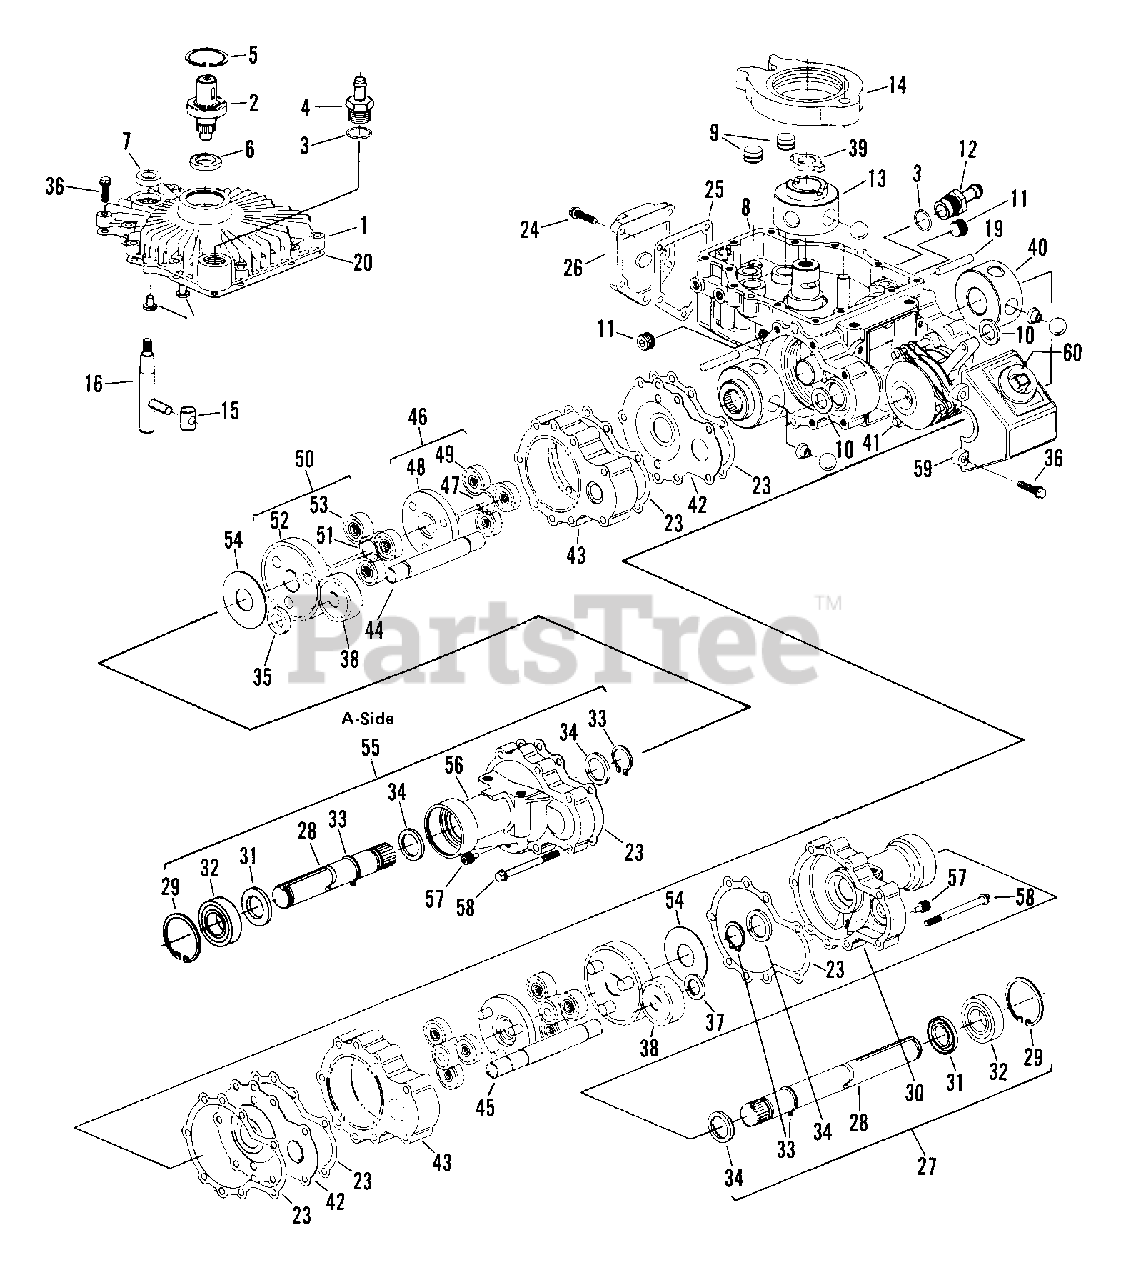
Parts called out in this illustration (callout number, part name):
1	COVER, SUBASSEMBLY
2	INPUT SHAFT SUBASSEMBLY
4	ADAPTER, RESERVOIR, 90 DEGREE
5	RING RETAINING, INT
6	SEAL, INPUT SHAFT
7	SEAL, CONTROL SHAFT
8	HOUSING SUBASSEMBLY
9	PISTON, DAMPENING SUBASSEMBLY
10	SEAL, BRAKE SHAFT
11	PLUG, SOCKET PIPE
12	ADAPTER, RESERVOIR, 3/8 ID
13	PUMP, ROTOR BALL SUBASSEMBLY
14	CAM RING SUBASSEMBLY
16	CONTROL SHAFT SUBASSEMBLY
17	O-RING PLUG SUBASSEMBLY
20	GASKET, COVER
23	GASKET, AXLE HOUSING
24	SCREW, 1/4 -20 HEX FLANGE
25	GASKET, VALVE COVER
26	VALVE COVER
27	AXLE HOUSING SUBASSEMBLY - B
28	SHAFT, AXLE - B
28	SHAFT, AXLE - A
29	RETAINING RING, INT.
30	HOUSING, AXLE - B
31	SEAL, AXLE SHAFT
32	BEARING, AXLE SHAFT
33	RETAINING RING, EXT. - B
34	WASHER, THRUST
35	AXLE HOUSING SUBASSEMBLY - A
36	SCREW, 1/4-20 SELF TAP
37	AXLE HOUSING SUBASSEMBLY - B
38	BRAKE GEAR
40	MOTOR ROTOR-BALL SUBASSEMBLY
41	BRAKE ASSEMBLY - 50 DEGREE
42	PLATE, WEAR
43	RING GEAR SUBASSEMLBY
44	BRAKE SHAFT - A
45	BRAKE SHAFT - B
46	PLANETARY GEAR, FIRST S/A
47	SUN GEAR, FIRST, 18T
48	PRIMARY CARRIER, S/A 18T
49	PLANET GEAR, FIRST, 18T, S/A
50	PLANETARY GEAR, SECOND S/A
51	SUN GEAR, SECOND, 18T
52	SECONDARY CARRIER, S/A 18T
53	PLANET GEAR, SECOND, 18T S/A
54	AXLE HOUSING SUBASSEMBLY - A
54	AXLE HOUSING SUBASSEMBLY - B
55	AXLE HOUSING SUBASSEMBLY - A
56	HOUSING, AXLE - A
57	PLUG MAGNETIC
58	SCREW, 1/4-20 HEX FLANGE
59	COVER, BRAKE
60	DUST BOOT
